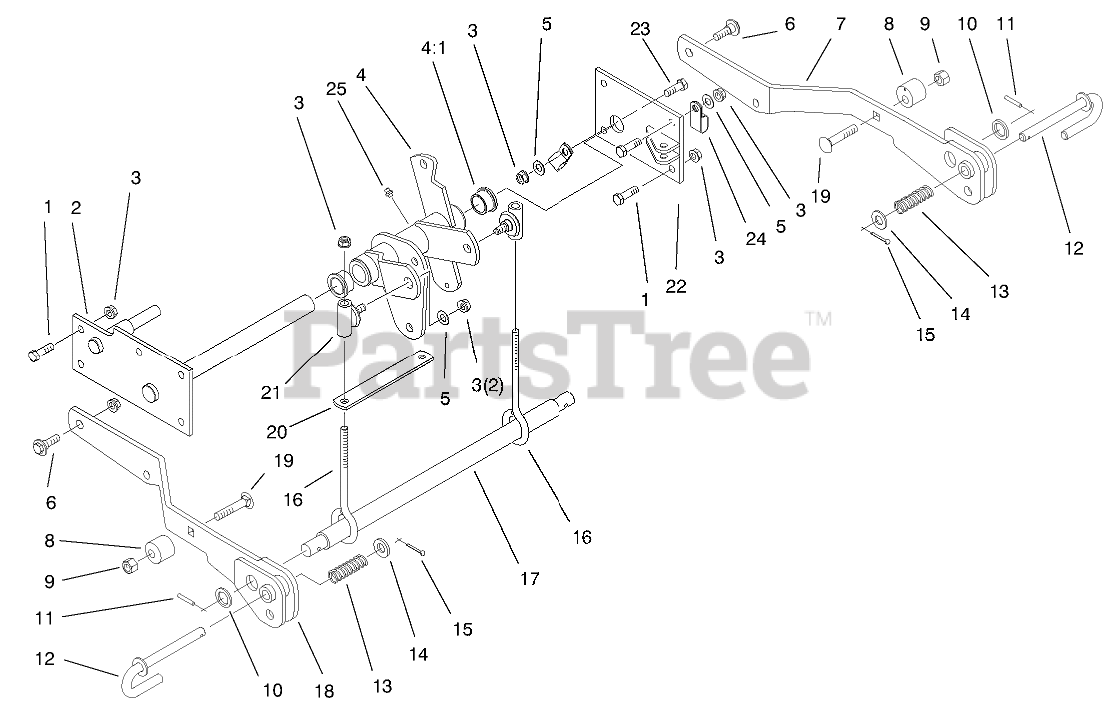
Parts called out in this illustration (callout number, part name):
1	SCREW-HH
2	SUPPORT-LIFT, DECK
3	NUT-LOCK, NI
4	BELLCRANK & BUSHING ASM
4:1	BUSHING-FLANGED
5	WASHER-FLAT
6	BOLT-SHOULDER
7	ARM-LIFT, LH
8	STOP-LIFT, ADJ.
9	NUT-LOCK, NI
10	WASHER-FLAT
11	PIN-ROLL
12	PIN - J
13	SPRING-COMPRESSION
14	WASHER-FLAT
15	PIN-COTTER
16	ROD - LIFT
17	BAR-LIFT
18	Arm-Lift, RH
19	SCREW-CARR
20	SPACER-STRAP
21	WA - LIFT SLEEVE
22	WA - CYLINDER SUPPORT
23	SCREW-HH
24	CLAMP-TUBE
25	FITTING-GREASE
